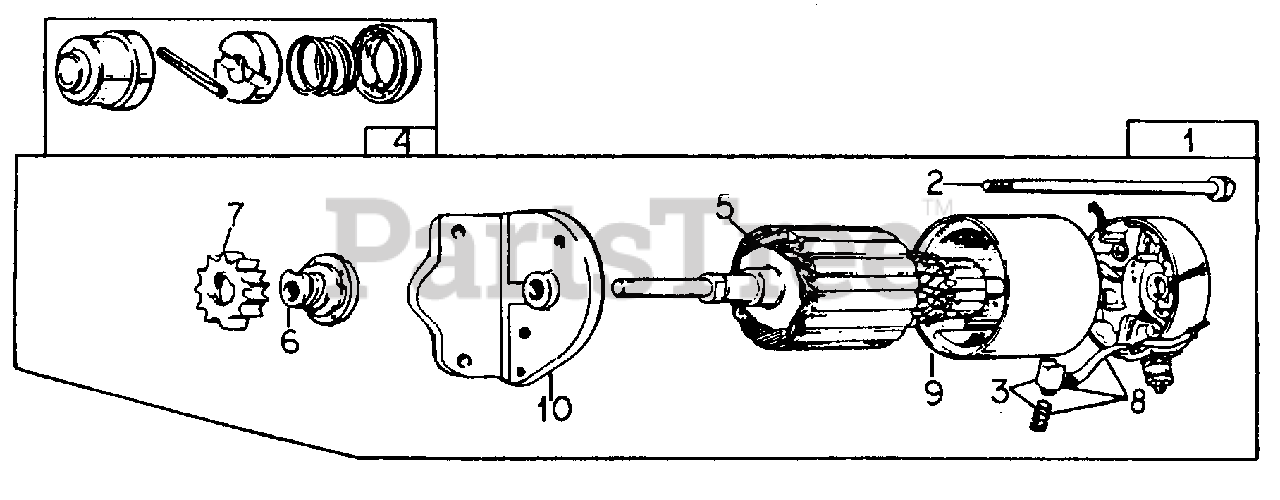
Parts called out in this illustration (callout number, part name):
1	Starter Assy
3	Set, Brush
4	Kit, Pinion Spring
5	Armature Assy
6	Clutch Assy, Starter
7	Gear, Starter Clutch
8	Cap Assy, End
10	Cap, Drive End
